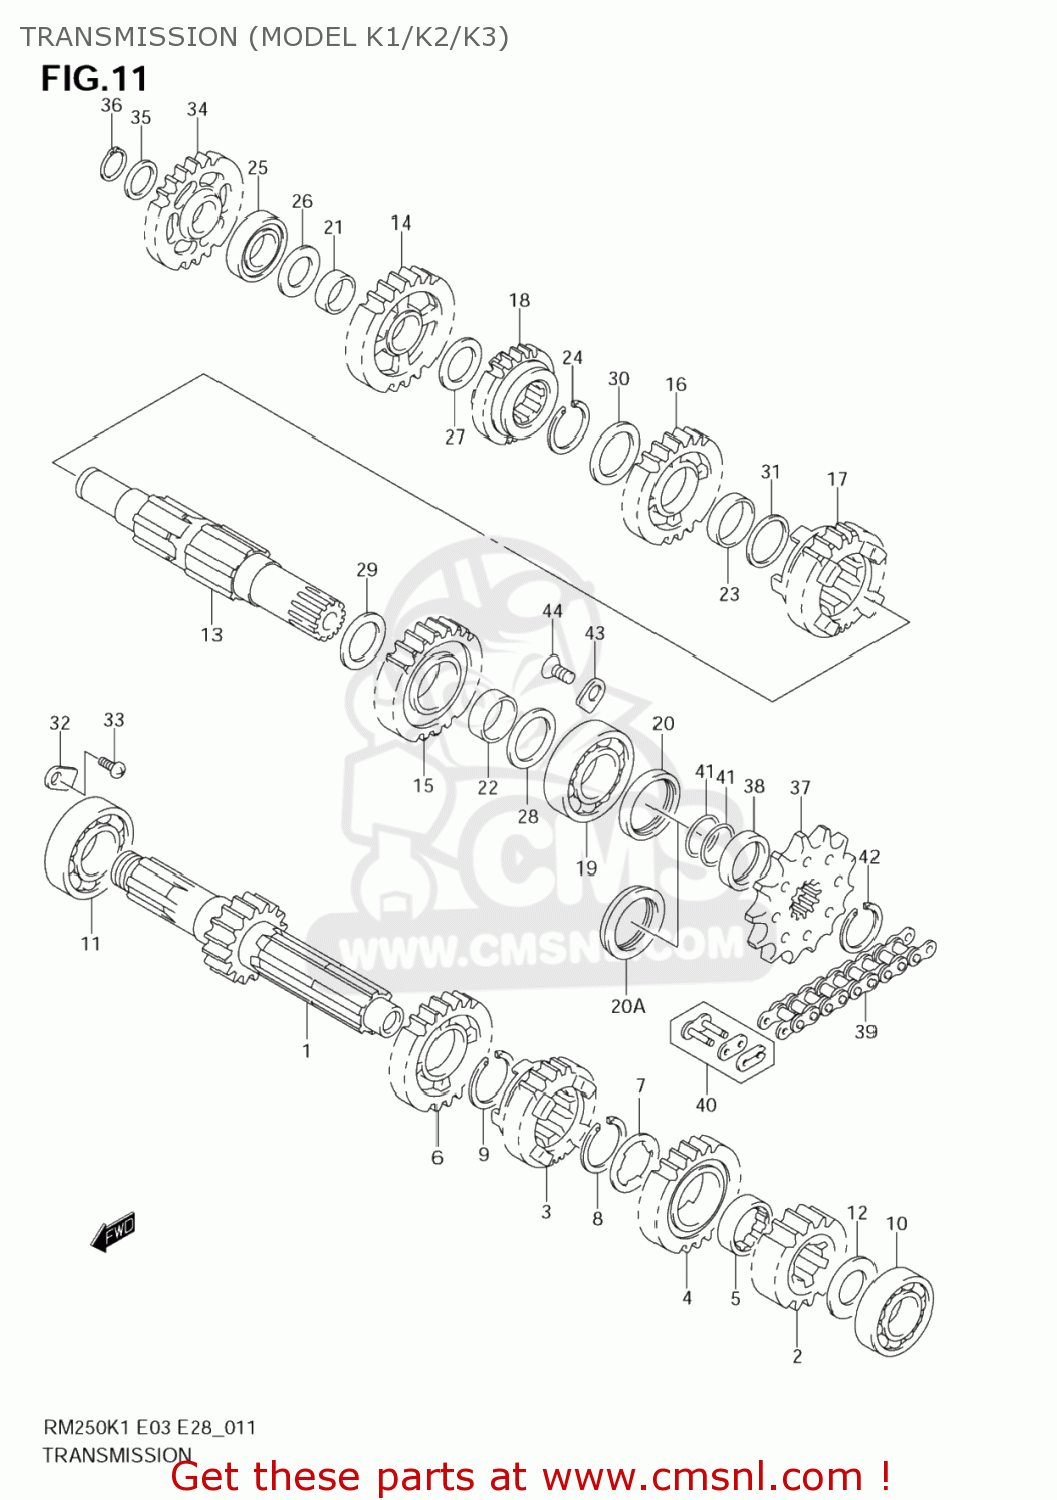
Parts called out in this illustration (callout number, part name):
1	SHAFT,COUNTER(NT:15)
2	GEAR,2ND DRIVE(NT:17)
3	GEAR,3RD DRIVE
4	GEAR,FOURTH DRIVE (NT:21)
5	BUSH,4TH DRIVE GEAR
6	GEAR,5TH DRIVE(NT:23)
7	WASHER,LOCK
8	CIRCLIP
9	CIRCLIP
10	BEARING
11	BEARING
12	SHIM(17X30X1)
13	SHAFT,DRIVE
14	GEAR,1ST DRIVEN(NT:27)
15	GEAR,2ND DRIVEN(NT:25)
16	GEAR,3RD DRIVEN(NT:23)
17	GEAR,4TH DRIVEN(NT:21)
18	GEAR,5TH DRIVEN(NT:20)
19	BEARING(22X56X15)
20	SEAL,OIL(28X38X6)
20A	SEAL,OIL(28X38X7.5)
21	BUSH(20X24X10)
22	BUSH(25X28X10)
23	BUSH(25X28X10)
24	CIRCLIP
25	BEARING(17X40X12)
26	SHIM(17X30X1)
27	SHIM(20X30X1)
28	SHIM(22X34X1.5)
29	SHIM(25X34X1)
30	SHIM(25X34X1)
31	SHIM
32	RETAINER
33	SCREW
34	GEAR,KICK STARTER IDLE(NT:27)
35	SHIM(17X24X0.5)
36	CIRCLIP,17MM
37	SPROCKET,ENGINE (NT:13)
38	SPACER,ENGINE SPROCKET
39	CHAIN(DID520DMA2,112L)
40	JOINT SET,CHAIN
41	O RING(D:1.9,ID:19.8)
42	CIRCLIP
43	RETAINER,COUNTER BEARING,R
44	SCREW
